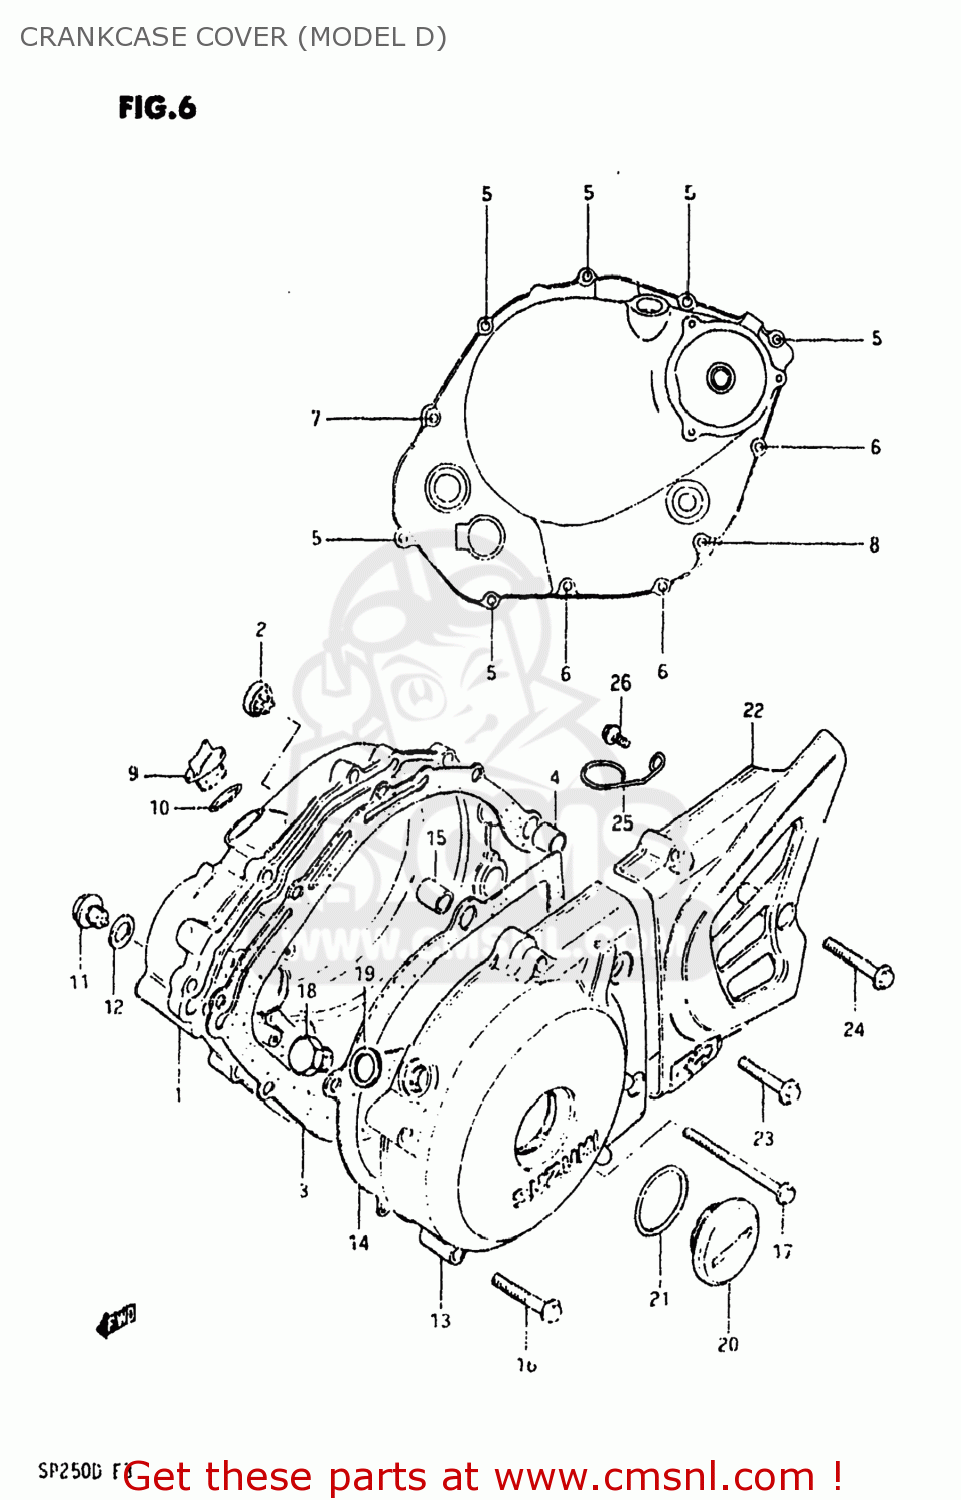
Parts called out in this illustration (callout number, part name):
1	COVER,CLUTCH
2	LENS,OIL LEVEL CHECK
3	GASKET,CLUTCH COVER (MCA)
4	PIN
5	BOLT (6X25)
6	BOLT (6X35)
7	BOLT (6X40)
8	BOLT (6X45)
9	PLUG
10	O RING(D:3.1,ID:16.8)
11	PLUG (14X12)
12	GASKET(14X19.2X2) (NAS)
13	COVER
14	GASKET,MAGNETO COVER (MCA)
15	PIN
16	BOLT (6X35)
17	BOLT 6X50
18	PLUG(12X9)
19	GASKET(12.1X16.2X3.7) (NAS)
20	PLUG
21	O RING(D:3.1,ID:32.7)
22	COVER,SPROCKET
23	BOLT (5X30)
24	BOLT (5X35)
25	GUIDE
26	BOLT
